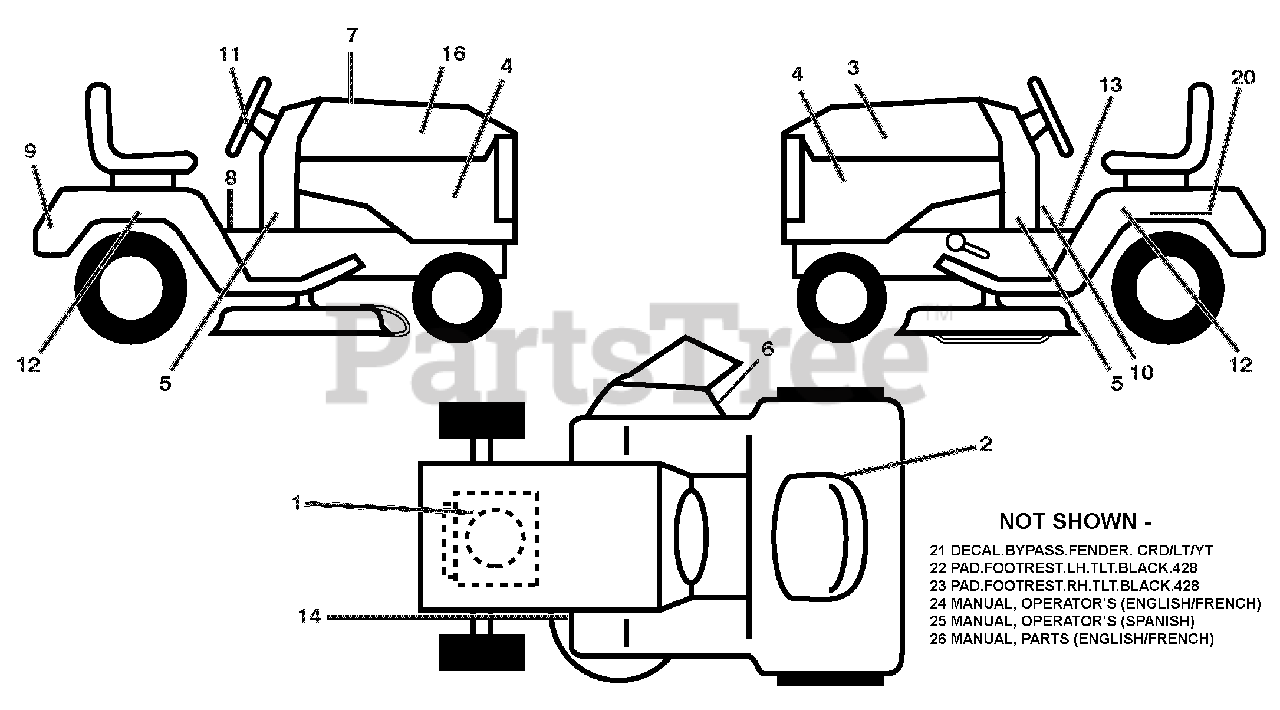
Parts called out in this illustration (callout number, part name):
1	Decal Fender Service
2	Decal Fender Service
3	DECAL.HOOD.LH.3HIGH.ARIENS
4	DECAL.SDPNL.PWRDBY KOHL.ARIENS
5	DECAL.DASH.LWR.18HP.ARIENS
6	DECAL.MOWER.WARN.KEEP HAND AWY
7	DECAL.RPL.KH(SNGL).TLW.42.PMST
8	DECAL.FENDER.WARNING.ENG/FR.07
9	DECAL.FENDER.REAR.ARIENS
10	Decal, Spark Arrester
11	DECAL.WHEEL.STEER.ARIENS
12	DECAL.FENDER.SIDE.HYDRO.ARIENS
13	Decal, Flag
14	DECAL.V-BELT.SCH.42/46"MEC/ELE
16	DECAL.HOOD.RH.3HIGH.ARIENS
20	DECAL.BAT.DAN/POI P/L SYM.WPN
